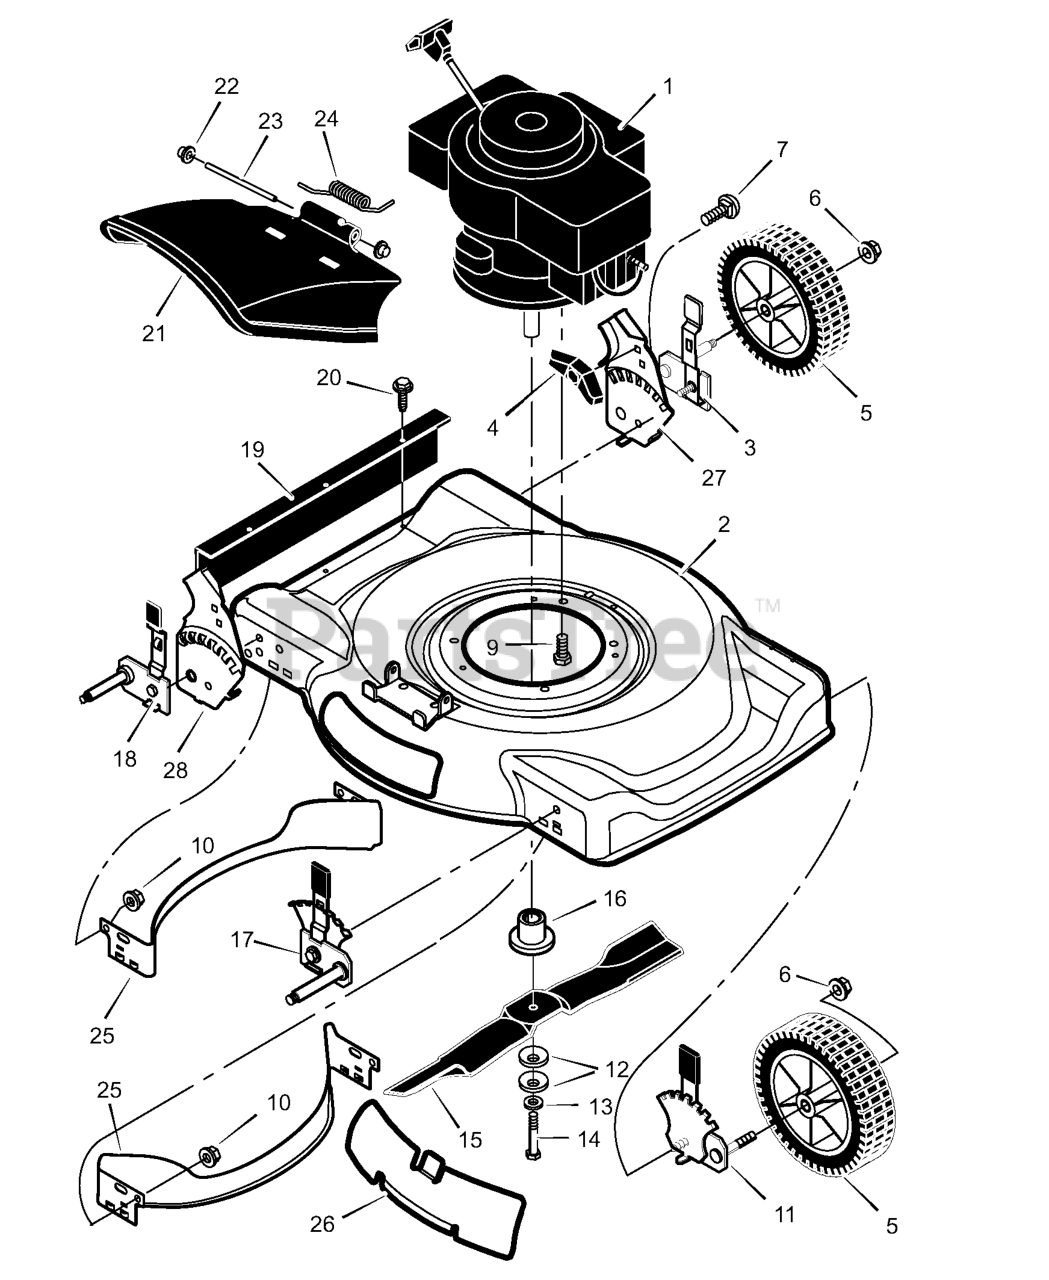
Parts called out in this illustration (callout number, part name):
1	Engine
2	Housing
3	Height Adjuster, Left Rear
5	Wheel and Tire
6	Locknut, Flange
7	Bolt, Carriage
9	Bolt, Engine
10	Nut
11	Height Adjuster, Left Front
12	Washer, Belleville
14	Bolt, Hex
16	Adapter, Blade
17	Height Adjuster, Right Front
18	Height Adjuster, Right Rear
19	Guard, Rear
21	Deflector, Chute
22	Push-On Cap
23	Pin, Pivot
26	Plate, Mulcher
27	Bracket, Left Handle
28	Bracket, Right Handle
